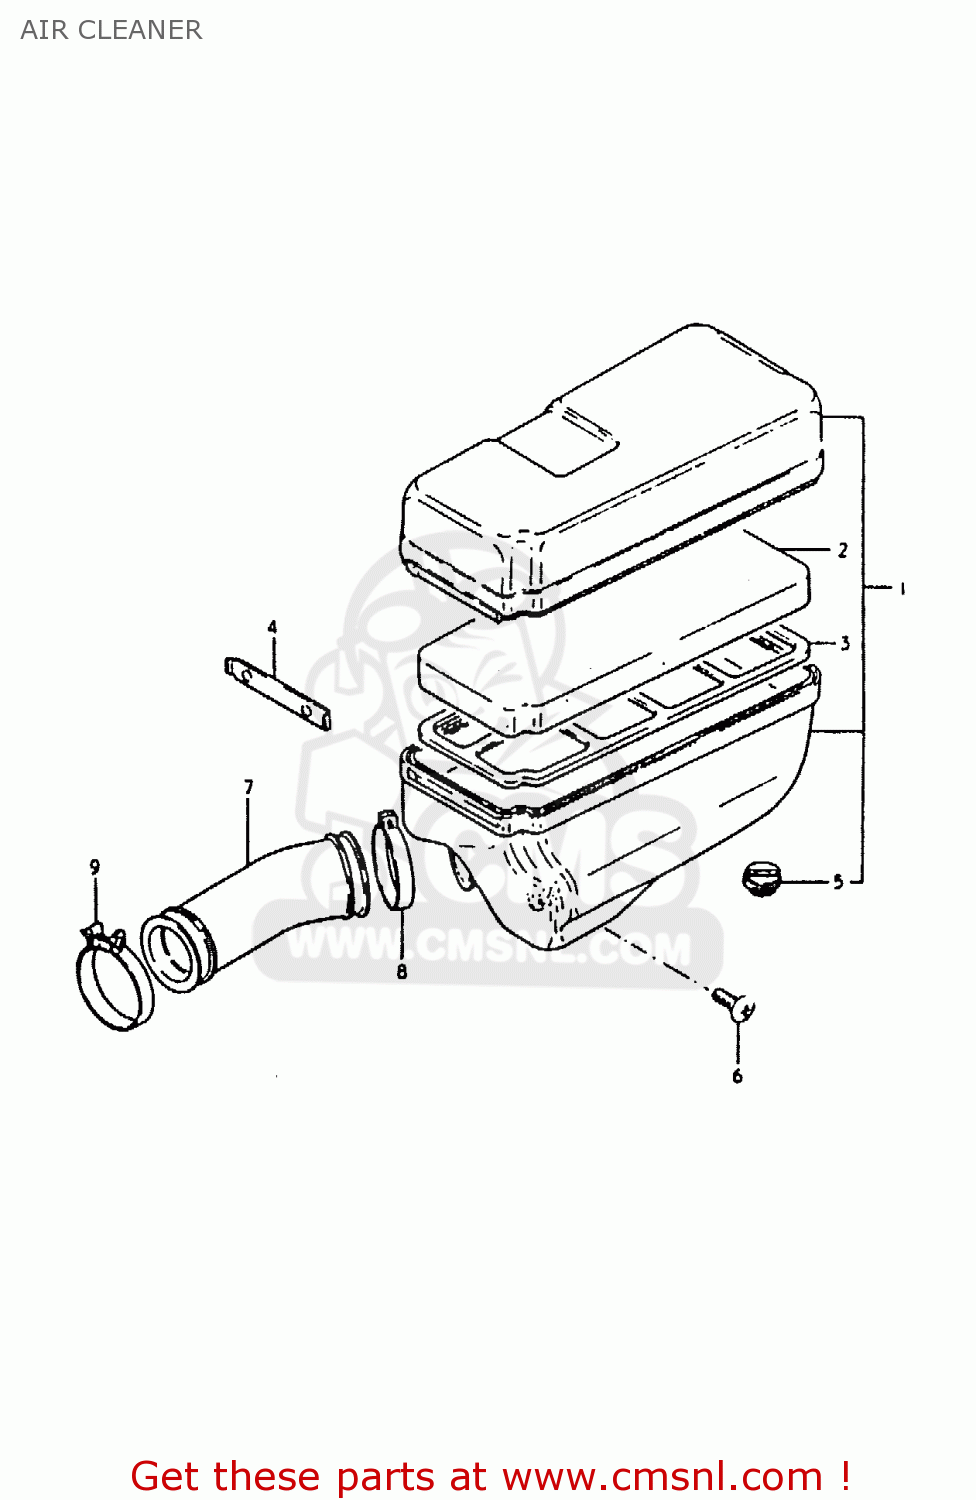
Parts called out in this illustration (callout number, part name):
1	CLEANER ASSY,A
2	FILTER
3	HOLDER
4	SLIDER
5	CAP,DRAIN
6	SCREW
7	TUBE,AIR CLEANER OUTLET
8	CLAMP
9	CLAMP
